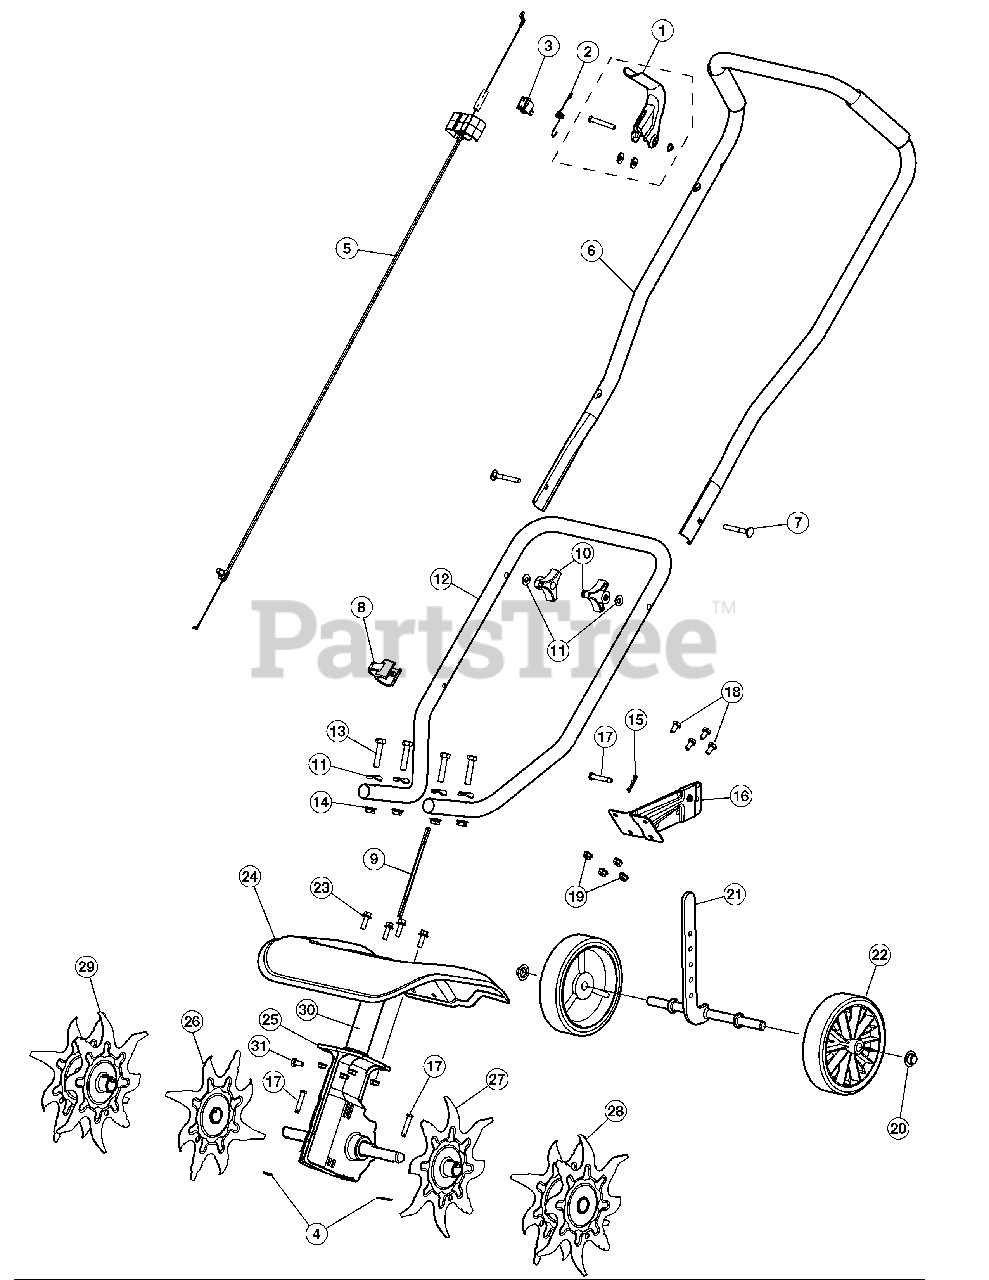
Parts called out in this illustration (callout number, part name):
1	Throttle Control
2	Throttle Spring
3	On/Off Switch
5	Throttle Cable
6	Upper Handle
8	Cable Tie
9	Flex Shaft
11	Washer
13	Screw
15	Cotter Pin
16	Tailpiece Bracket Assembly
17	Clevis Pin
18	Cap Screw
21	Wheel Support Bracket Assembly
22	Wheel
24	Tine Shield
25	Gear Box Assembly
26	Tine (Right Inner)
27	Tine (Left Inner)
28	Tine (Left Outer)
29	Tine (Right Outer)
30	Drive Shaft Housing
31	Sleeve Retaining Bolt
